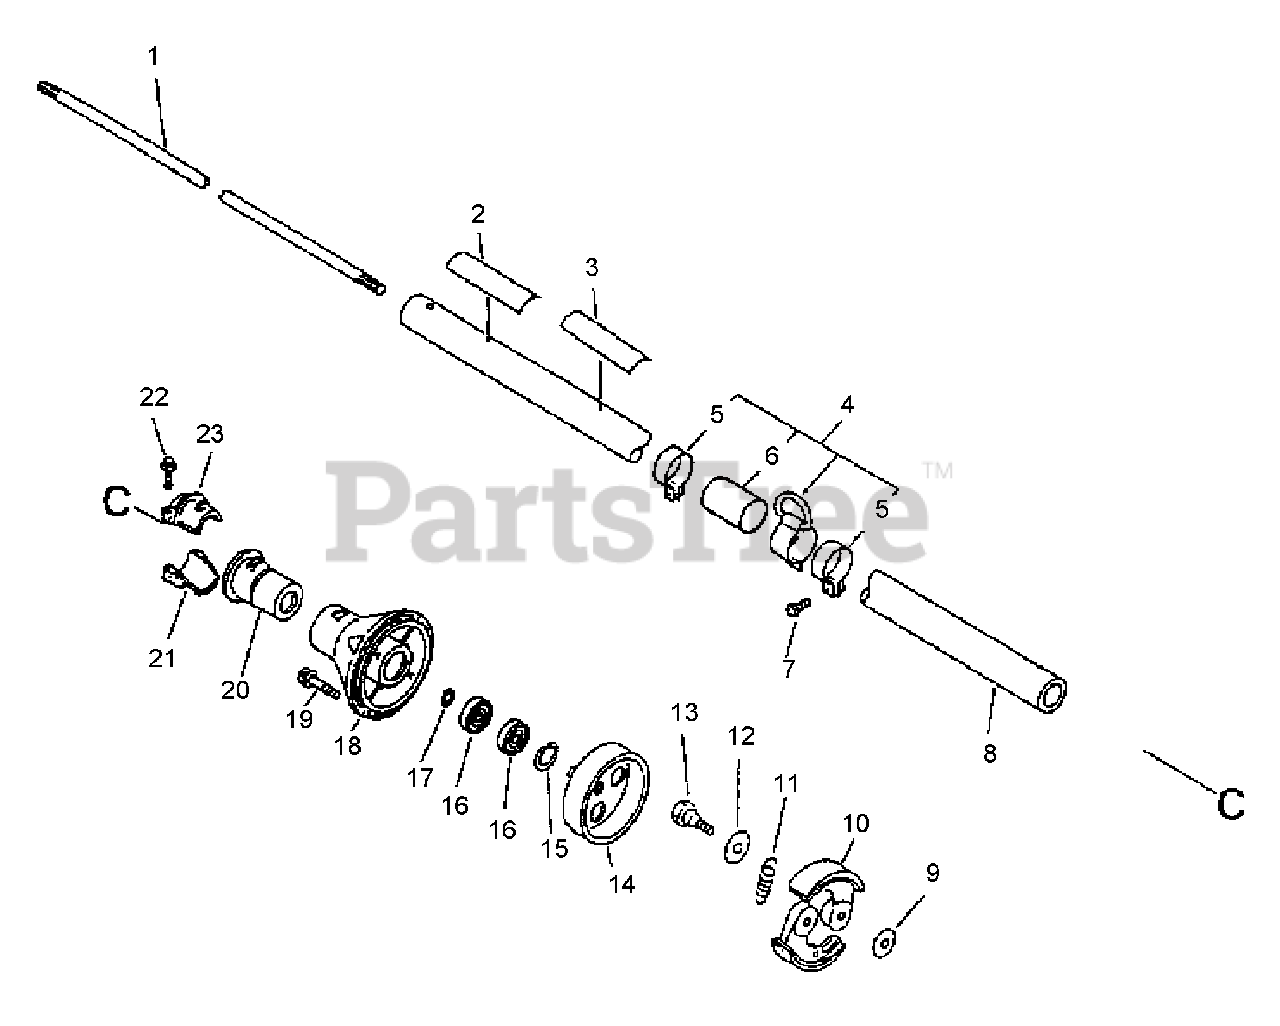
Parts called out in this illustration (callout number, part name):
1	DRIVESHAFT - SOLID
2	LABEL - CAUTION
3	LABEL - CAUTION -- SPANISH
4	HANGER KIT
5	HOOK
6	COLLAR
7	SCREW - 5X14
8	MAIN PIPE ASSY
10	SHOE, CLUTCH
11	SPRING, CLUTCH
13	BOLT, CLUTCH
14	DRUM, CLUTCH
15	RING, RETAINING - 28
16	BEARING, BALL - 6001
17	RING, RETAINING - 12
18	CASE, CLUTCH
19	SCREW - 5X20
20	CUSHION
21	CLAMP, MAIN PIPE
21	CLAMP, MAIN PIPE - LOWER
22	BOLT - 5X25
23	CLAMP, MAIN PIPE - UPPER
